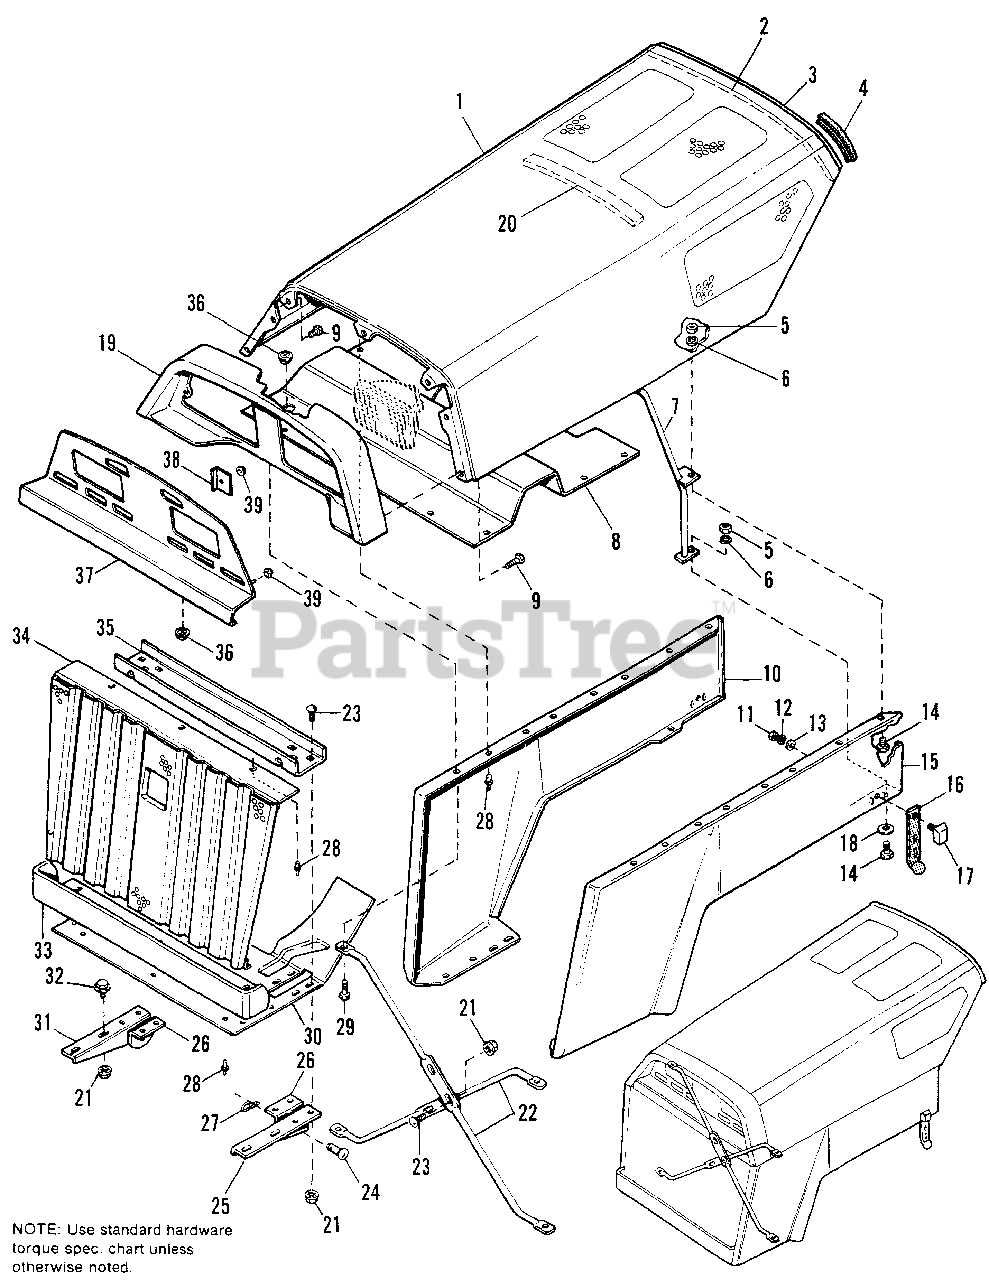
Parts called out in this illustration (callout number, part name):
2	SEAL, Hood, Rear
3	DECAL, Hood Rear
4	MOLDING, Hood
5	NUT, Hex, 1/4-20
6	LOCKWASHER, 1/4
7	SUPPORT ROD ASSY., Hood
8	SHIELD, Muffler
9	SCREW, Hex, Taptite, 1/4-20 x 1/2
10	PANEL, Side, R.H.
11	NUT, Hex, #10-24
12	LOCKWASHER, #10
13	WASHER, 13/64 ID x 3/4
14	CAPSCREW, Hex Hd., 1/4-20 x 1/2
15	PANEL, Side, L.H.
16	STRAP, Hood
17	COVER ASSY., Hood Strap
18	WASHER, Plain, 1/4 x 5/8 x 3/64
19	FRAME, Headlamps
20	SEAL, Hood Support
21	NUT, Hex, Flange Whizlock 1/4-20
22	BRACE, Hood, Front
23	BOLT, Carriage, 1/4-20 x 3/4
24	PIN, Lock (Clevis)
25	HINGE, Hood, Outer, L.H.
26	HINGE, Hood, Inner
27	PIN, Quick, 3/32 x 1-7/8
28	RIVET, Pop, 3/16
29	SCREW, Hex, Thd. Form, #14-3/4
30	SHIELD, Heat
31	HINGE, Hood, Outer, R.H.
32	SCREW, Hex, Fl. Whiz Lock, 1/4-20 x 3/4
33	BUMPER ASSY.
34	SCREEN ASSY., Grille (1691017, 1691018 only)
34	SCREEN ASSY., Grille (1691380, 1691381, 1691528, 1691710, 1691924, 1691926, 1691928, 1691953)
35	SUPPORT, Stop, Hood
36	BUSHING, Universal
37	HEADLAMP INSERT ASSY.
38	CLIP, Headlamps, Mounting
39	PALNUT, Hex, Lock, #10-24
